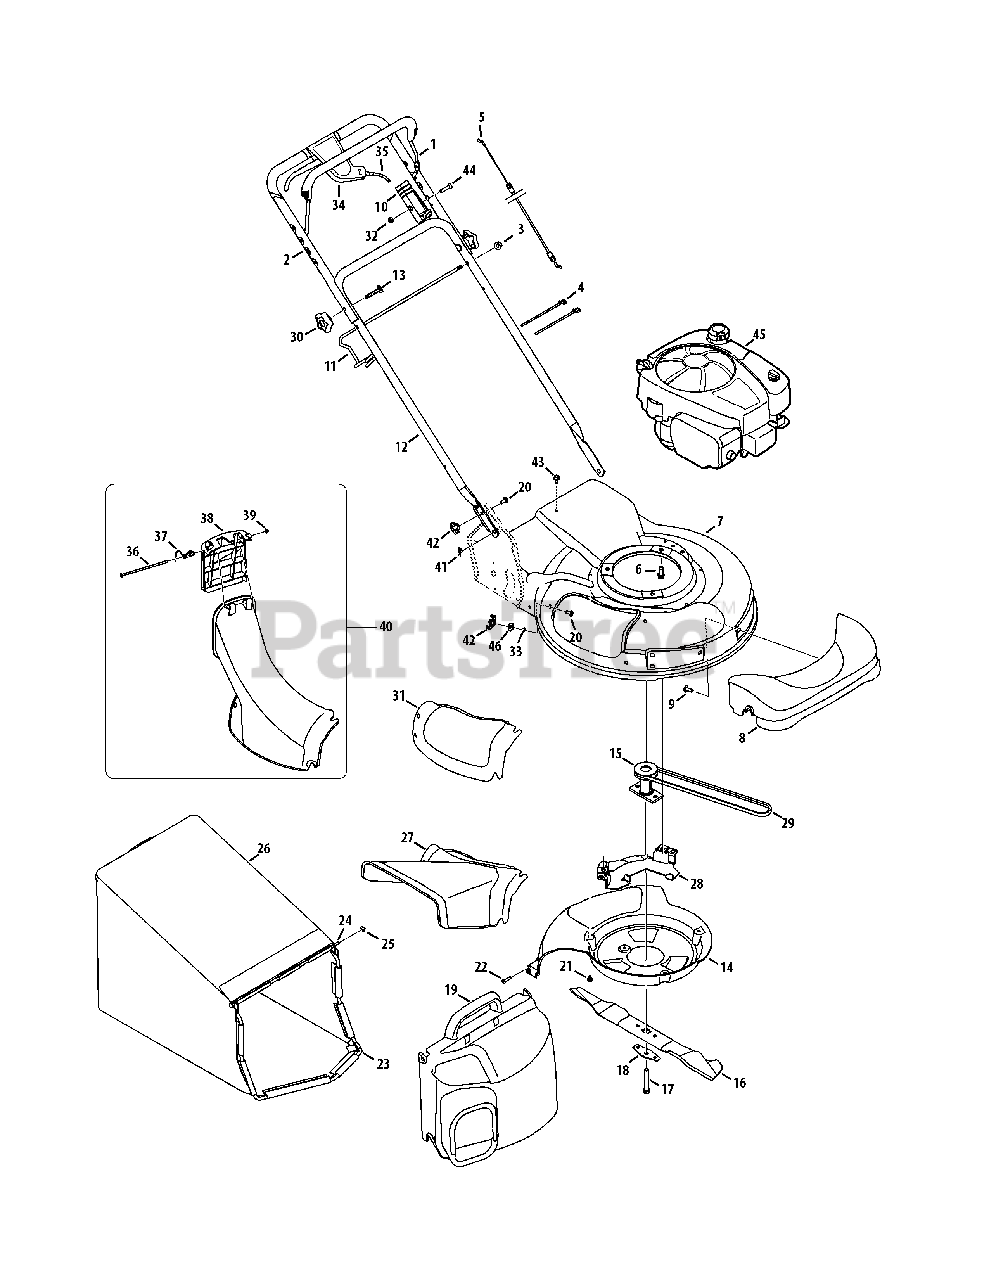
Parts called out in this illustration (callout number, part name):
1	Blade Control
2	Upper Handle
3	Flange Lock Nut, 5/16-18
4	Cable Tie
5	Control Cable
6	TT Screw, 3/8-16 x 1.00
7	21-inch Deck
8	Front Axle Cover
9	HL Screw, 5/16-14 x .750
10	Housing
11	Grass Bag Support Rod
13	Carriage Bolt 5/16-18 x 2
14	Rear Baffle
15	Blade Adapter
16	21-inch Mulching Blade
17	HH Cap Screw, 3/8-24 x 2.50
18	Bell Blade Spacer
19	Grass Bag Cover Assembly
20	Carriage Screw 1/4-20 x .75
21	TT Screw 1/4-20 x .375
22	HL Screw 1/4-15 x .75
23	Grass Bag Frame
24	Grass Bag Pivot Rod
25	Cap Speed Nut
26	Grass Bag Assembly
27	Side Discharge Chute
28	Belt Keeper
29	V-Belt
30	Star Knob
31	Mulch Cover
32	Hexlk Nut, 1/4-20
33	Push Nut
34	Drive Control Assembly
35	Drive Cable
36	Chute Door Pivot Rod
37	Torsion Spring
38	Top Discharge Door Chute
39	Push Cap
40	Top Discharge Chute Assembly
41	Cotter Pin
42	Wing Nut
43	TT Screw, 5/16-18 x .500
44	Screw, 1/4-20 x 1.310
45	Engine - 11P902-0881-B1
46	Flat Washer, .260 x .720 x .060
